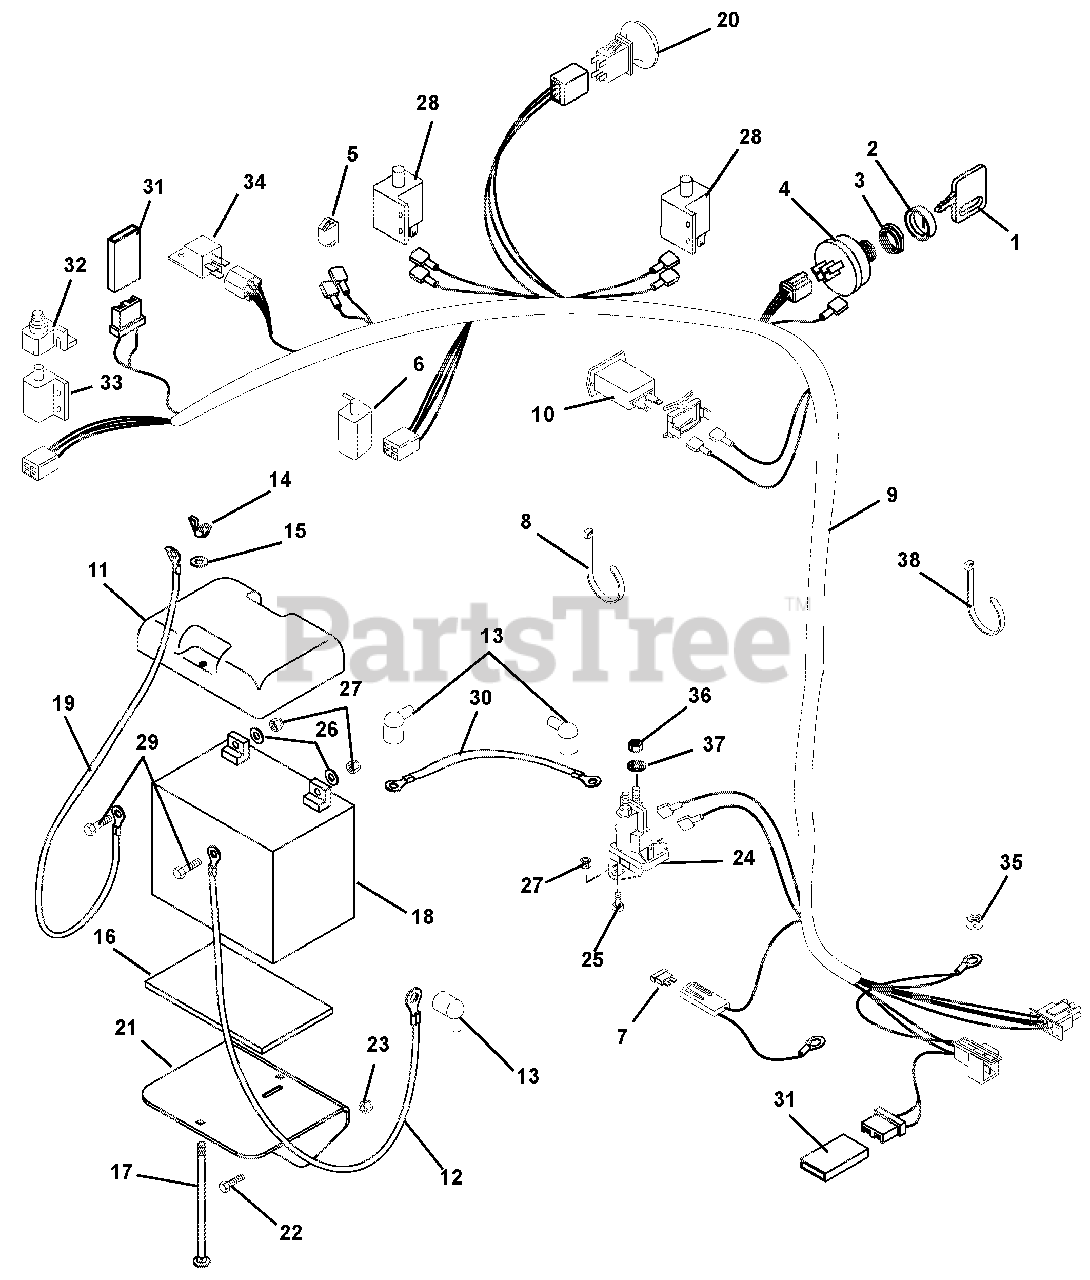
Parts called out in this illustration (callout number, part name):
1	Key- with Cap
2	Cap, Ignition Switch
3	Nut, Panel .625-32
4	Key Switch
5	Light, Indicator
6	Switch- Double Pole N.O./N.O.
7	Fuse-25 AMP
8	Tie Wrap-Black
9	Wire Harness
10	Hour Meter-Quartz
11	Cover-Battery
12	Cable, Positive Battery
13	Boot, Eyelet Terminal
14	Nut-Locking-Wing .25-20
15	Washer-Flat-Steel .281 x .625 x .065
16	Pad, Battery
17	Bolt-Round Head Square Neck .25-20 x 7.50 Grade 2
19	Cable, Negative Battery
20	Switch, Clutch With Retainer
21	Weldment, Battery Tray
22	Bolt-Hex .38-16 x 1.75 Grade 5
23	Nut-Locking-Nylon .38-16
24	Solenoid
25	Bolt-Hex .25-20 x .50 Grade 5
26	Washer-Flat-Steel .281 x .62 x .065
27	Nut-Locking-Flange .25-20 (108, 109)
28	Switch- Single Pole (N.O.)
29	Bolt-Hex .25-20 x .75 Grade 5
30	Starter Cable 6.75"
31	Diode-Connector Shell
32	Boot, Rubber
33	Switch, Interlock
34	Relay
35	Nut-Locking-Top-Flange .31-18
36	Nut- Jam .31-24
37	Washer-Locking .31
38	Tie Wrap
